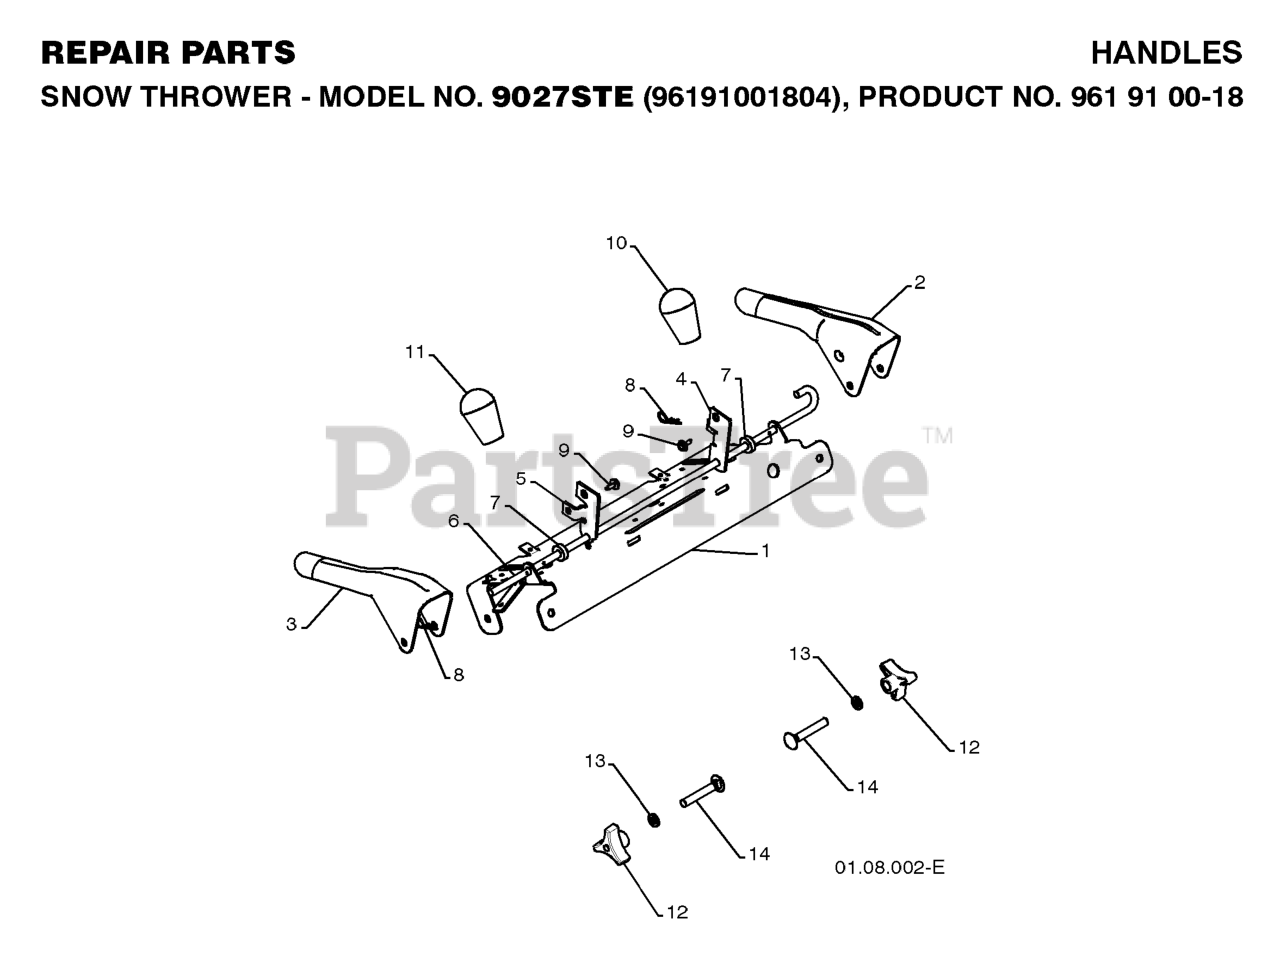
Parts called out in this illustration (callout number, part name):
1	PANEL.CONTROL.PNT.BLACK
2	LEVER.CONTROL.LH.PNT
3	LEVER.CONTROL.RH.PNT
4	ARM.TRACTION.ROD.YZ
5	ARM.IMPELLER.ROD.
6	BAIL.CONTROL.INTERLOCK
7	SPACER.CONTROL.LEVER
8	SPRING RETAINER
10	KNOB LEVER, BLACK
11	RED KNOB SHIFTER
12	KNOB.HANDLE.3/8.TRI-POINT.BLAC
13	WASHER
14	BOLT 3/8-16 X 2-1/4
